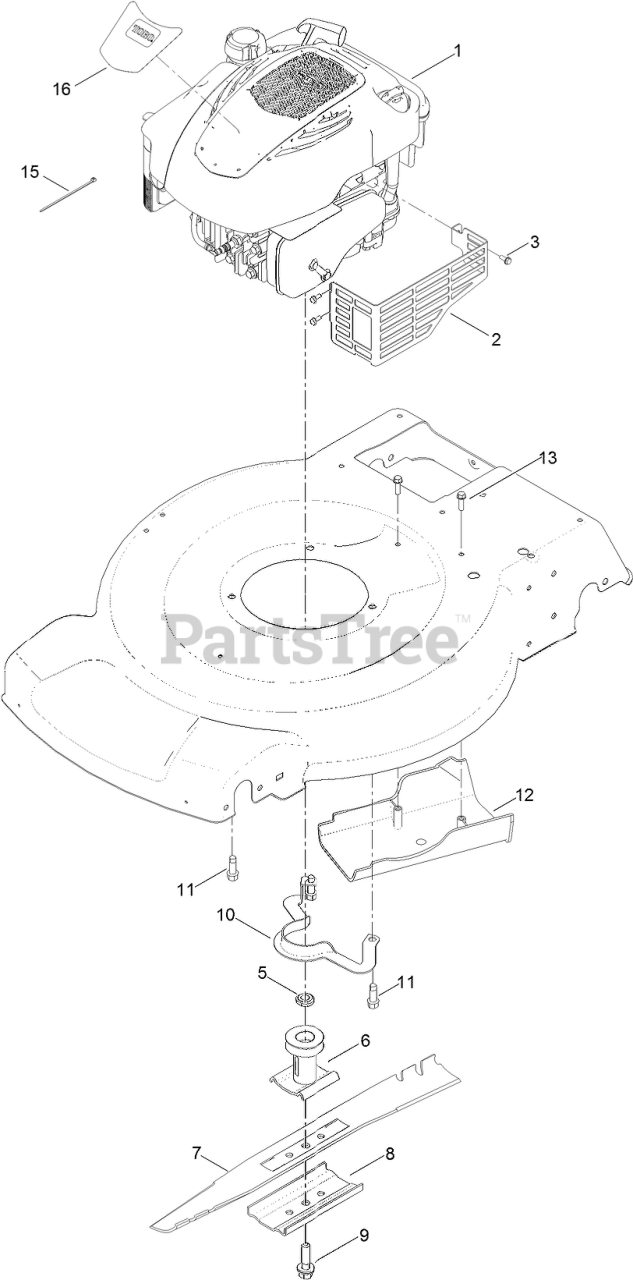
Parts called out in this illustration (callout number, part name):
2	SHIELD-MUFFLER
3	SCREW-TAPTITE
5	Spacer-Driver
6	DRIVER-BLADE
7	BLADE
8	Accelerator-Blade
9	BOLT-BLADE
10	Guide-Belt
11	SCREW-TAPTITE
12	COVER-BELT
13	SCREW-HWH
15	TIE-CABLE, MOTOR
16	DECAL-SHROUD
